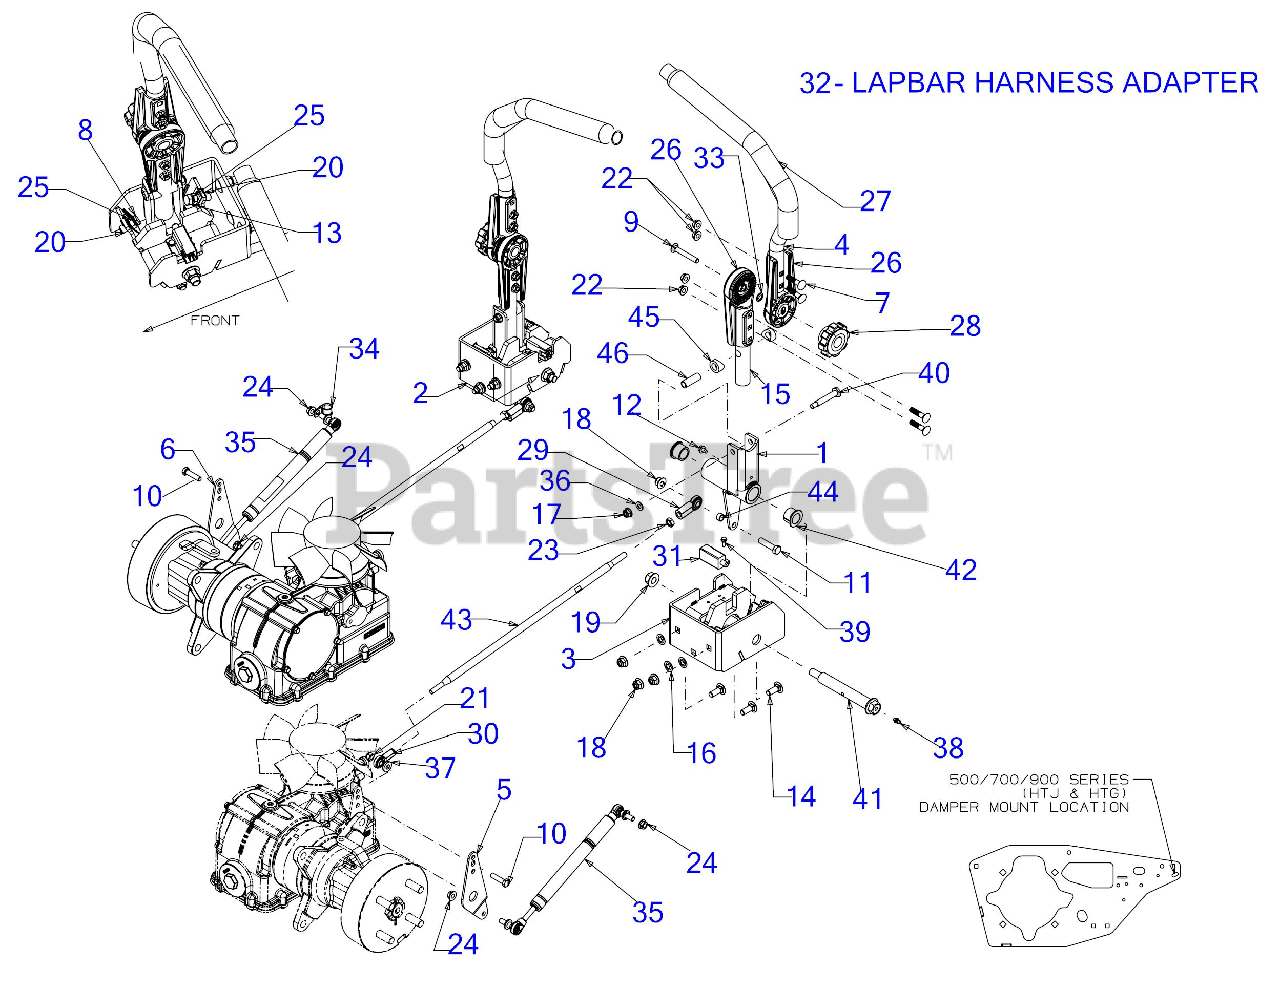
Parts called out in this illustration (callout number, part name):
1	LAPBAR PIVOT CONTROL ASSEMBLY
5	MOUNTING BRACKET (RH)
6	MOUNTING BRACKET (LH)
7	CARRIAGE BOLT 5/16-18 x 1.50
8	SCREW 3/8-16X1.0 GR5 SPEC
9	SCRE W5/16-18 x 2.25 GR5
10	SCREW 5/16-18 x 1.25 GR5
11	SCREW 3/8-16 x 1.50 GR8
12	SCREW 1/4-20 x .375
13	SCREW 3/8-16 x 1.25 GR5
14	CARRIAGE BOLT 3/8-16 x 1.00 GR5
17	FLANGE LOCK NUT 5/16-18
20	U NUT 3/8-16
21	HEX NUT
22	FLANGE NUT
23	HEX JAM NUT 3/8X24
24	HEX FLANGE NUT
26	HANDLE ADJUST
28	KNOB-5/16-18
29	BALL JOINT
30	END ROD- 5/16 (LH)
31	INTERLOCK SWITCH (NO/NC)
32	ADAPTER HARNESS - LAPBAR
35	DAMPENING CYLINDER
36	FLAT WASHER
37	FLAT WASHER
38	GREASE ZERT 1/4-28
39	SHOULDER SCREW
40	SHOULDER SCREW
41	SHOULDER BOLT 1.0 X 4.75 1/2-13
42	FLANGE BEARING
43	PUMP CONTROL ROD
45	NYLON SPACER
